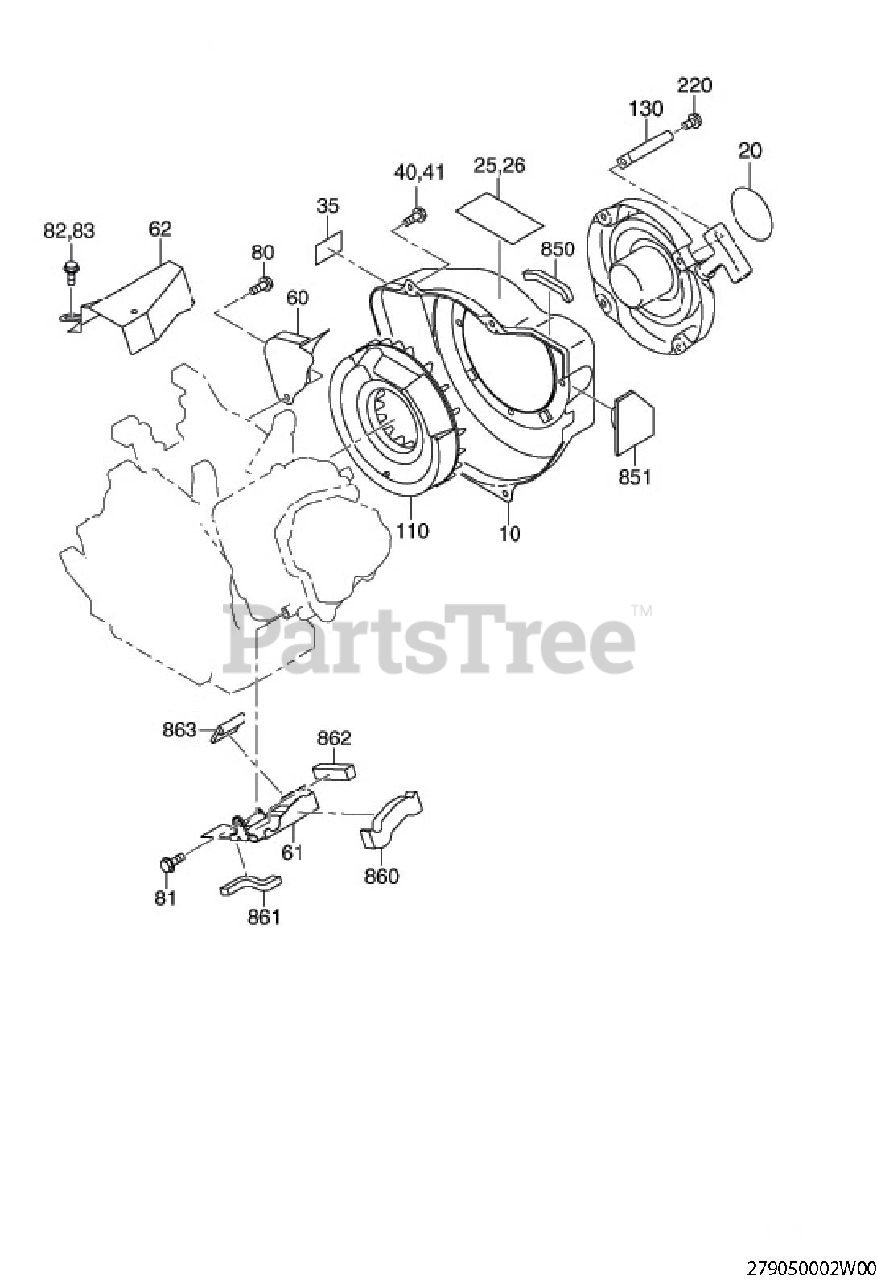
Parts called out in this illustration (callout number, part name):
10	BLOWER HOUSING CP
20	LABEL(TRADE MARK)
40	FLANGE BOLT
41	FLANGE BOLT
61	BAFFLE 2(HEAD)
81	FLANGE BOLT
220	FLANGE BOLT
